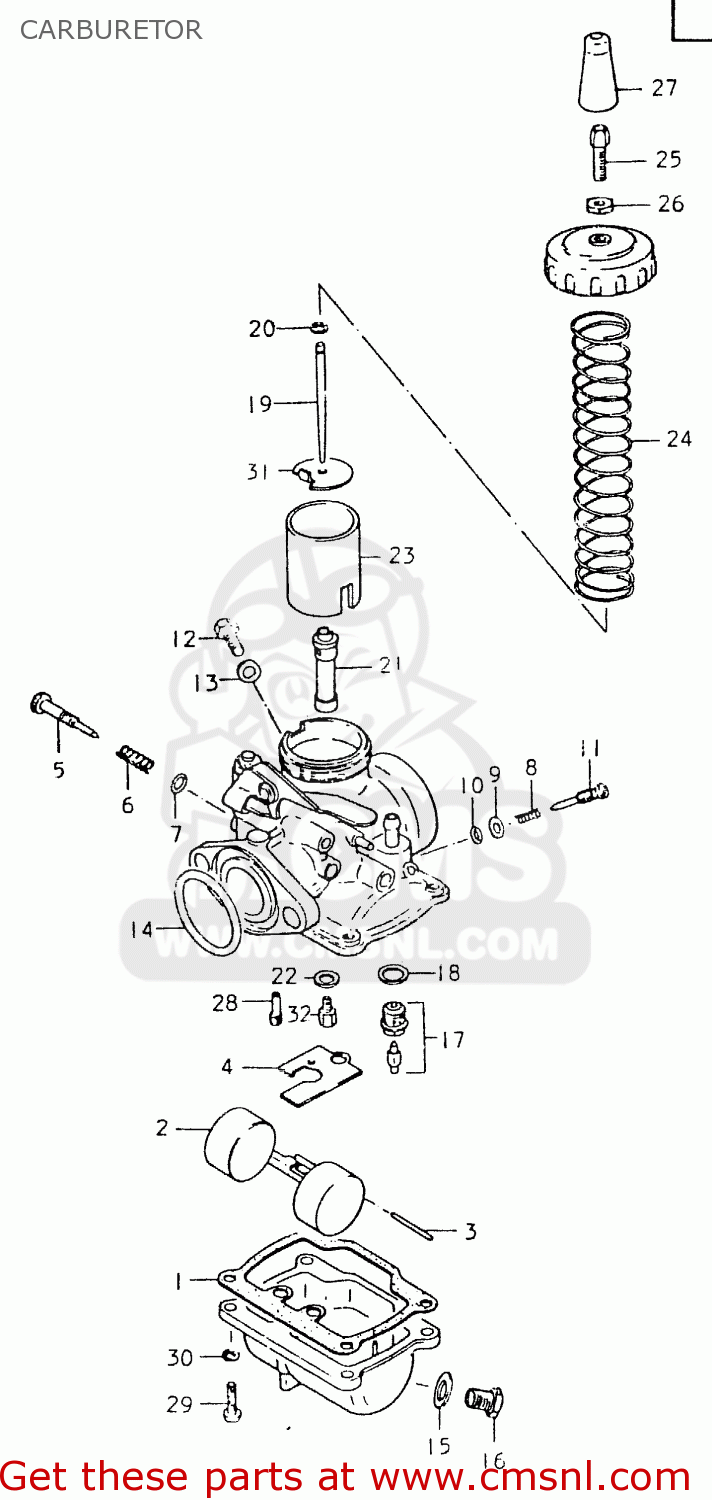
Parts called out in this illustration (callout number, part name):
1	GASKET,FLOAT CHAMBER (NAS)
2	FLOAT
3	PIN,FLOAT
4	PLATE
5	SCREW,THROTTLE STOP
6	SPRING,PILOT
7	O-RING
8	SPRING
9	WASHER,PILOT AIR SCREW
10	O RING
11	SCREW,PILOT AIR
12	BOLT
13	GASKET,THRO VALVE INSPECTION (NAS)
14	O RING
15	GASKET,DRAIN,PLUG (NAS)
16	PLUG
17	VALVE ASSEMBLY,NEEDLE
18	GASKET,VALVE SEAT (NAS)
19	NEEDLE,JET
20	CLIP
21	JET,NEEDLE
22	WASHER
23	VALVE,THROTTLE
24	SPRING, THROTTLE VALVE
25	ADJUSTER,CABLE
26	NUT
27	CAP
28	JET
29	SCREW
30	LOCK WASHER
31	SEAT,THROTTLE VALVE SPRING
32	JET,MAIN 85
